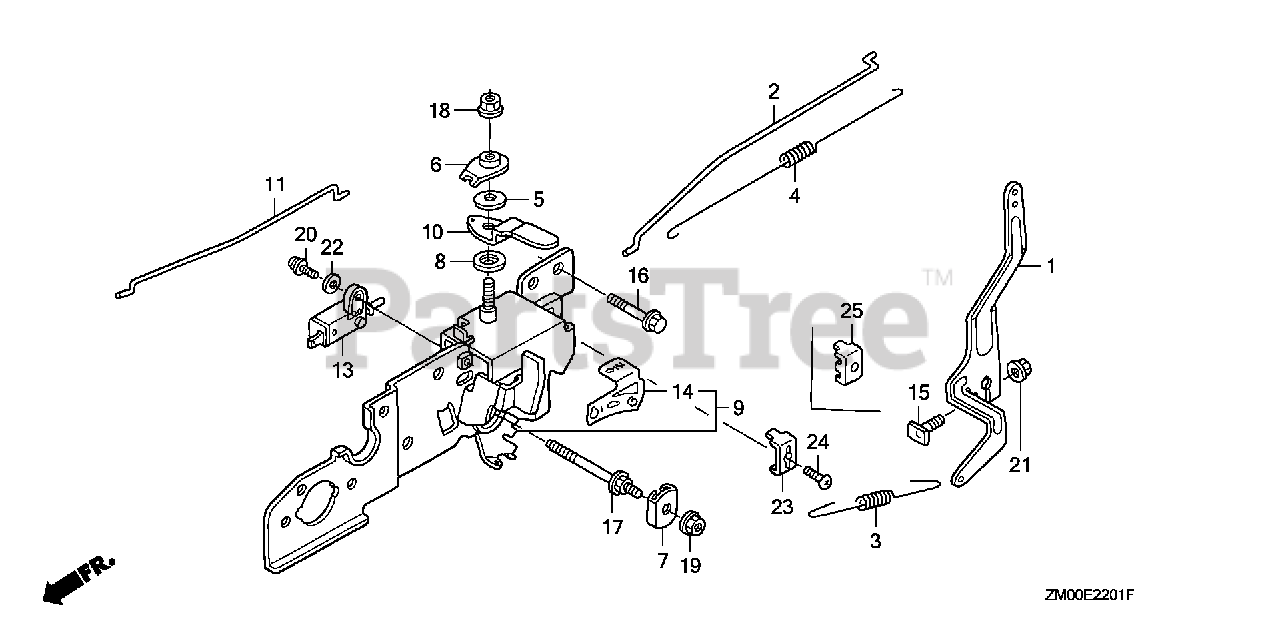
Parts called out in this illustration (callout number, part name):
1	ARM, GOVERNOR
2	ROD, GOVERNOR
3	SPRING, GOVERNOR
4	SPRING, THROTTLE RETURN
5	SPRING, LEVER
6	WASHER, CONTROL LEVER
7	PLATE, LEVER CENTER
8	SPACER, CONTROL LEVER
9	BASE, CONTROL
10	LEVER, CHOKE
11	ROD, CHOKE
13	SWITCH ASSY., ENGINE STOP (N.O)
14	MARK, THROTTLE INDICATION
15	BOLT, GOVERNOR ARM
16	BOLT, FLANGE (6X32) (CT200)
17	BOLT, SPECIAL (6X45)
18	NUT, SELF-LOCK (6MM)
19	NUT, SELF-LOCK (5MM)
20	SCREW-WASHER (4X12)
21	NUT, FLANGE (6MM)
22	WASHER, PLAIN (4MM)
23	HOLDER, CABLE
24	SCREW, PAN (5X16)
